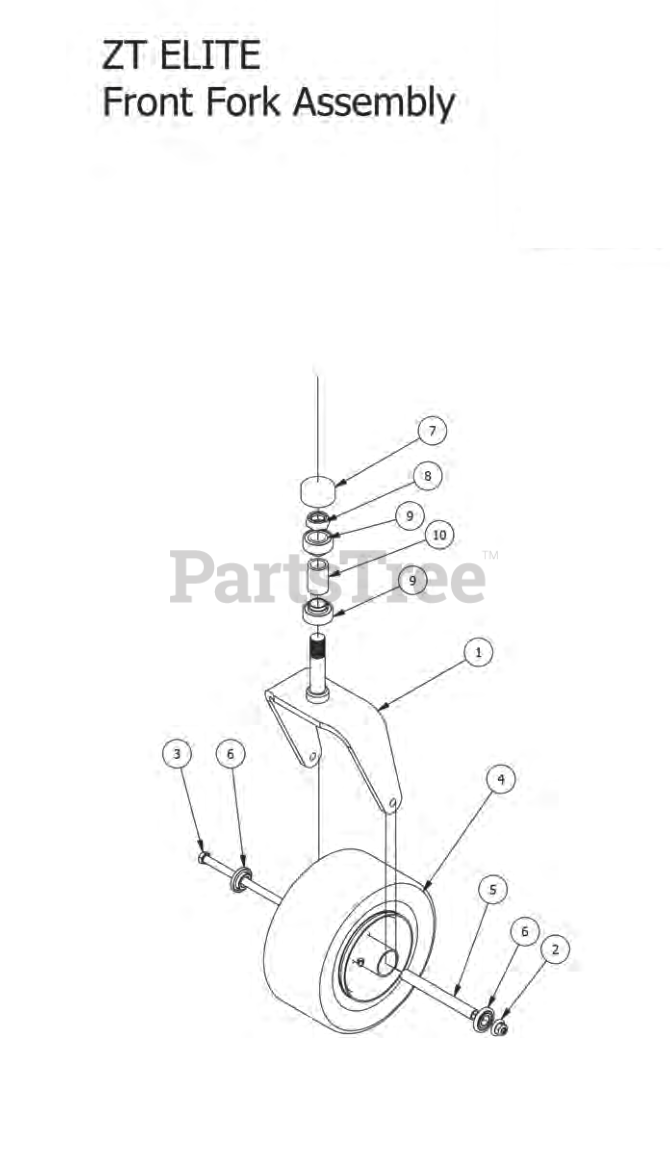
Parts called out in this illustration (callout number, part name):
1	Front Fork
2	1/2-13 Nylon Flange Nut-Orange
3	1/2" x 9" Bolt
4	Tire and wheel assembly
5	Front Wheel Spanner
6	Wheel Bearing
7	Rubber Bearing Cap
8	1" Fine Thread 1/2 Nut
9	Caster Bearing -MZ, 2009 & up
10	ZT/CZT Caster Bearing Spacer
